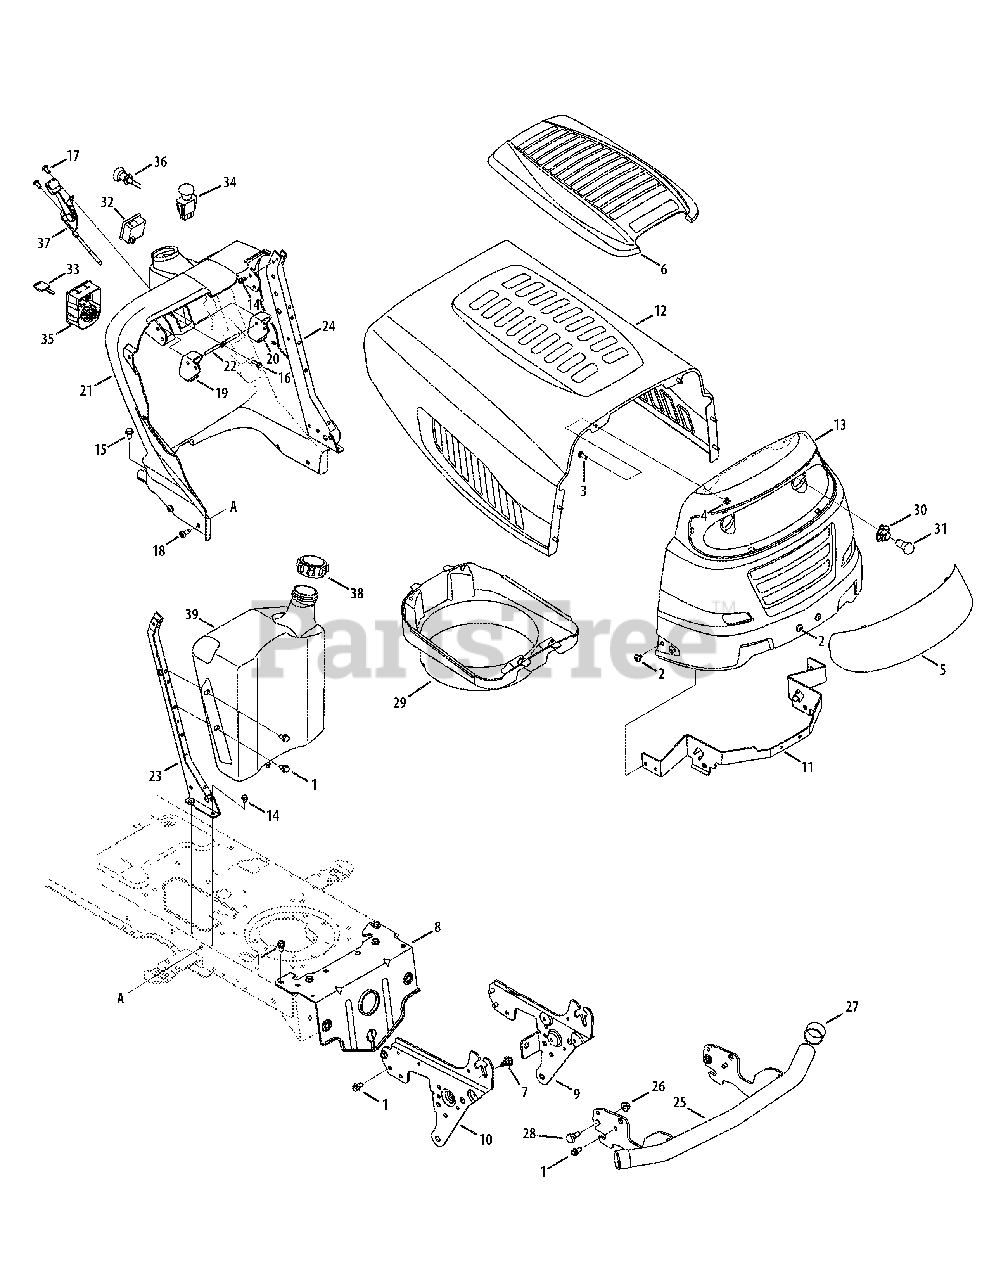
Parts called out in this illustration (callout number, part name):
1	Screw, 5/16-18 x .750
2	Screw, 5/16-18 x .375
3	Hex Cap Screw, 1/4-20 x.62
4	Flange Lock Nut, 1/4-20
5	Headlight Lens
6	Hood Cover, 5 Style
7	Shoulder Screw,.43 x.29
14	Self-tapping Screw, 1/4-20 x.5
15	Screw, 5/16-18 x .500
16	Self-tapping Screw, 1/4-15 x.75
17	Screw, 1/4-14 x.625
18	Screw, 5/16-18 x.75
19	Cruise Control Button
20	Parking Brake Button
21	Dash Panel
22	Brake/Cruise Pivot Rod
26	Flange Lock Nut, 3/8-16
28	Shoulder Bolt, 3/8-16
30	Headlight Socket
31	Lamp
32	Systems Ind. Monitor w/Hr. Mtr.
33	Ignition Key w/ plastic cover
33	Ignition Key w/o plastic cover
34	Electric PTO Switch
35	Ignition Switch
36	Choke Control Cable
37	Throttle Control/Cable
38	Fuel Cap
39	Fuel Tank, Three Gallon
